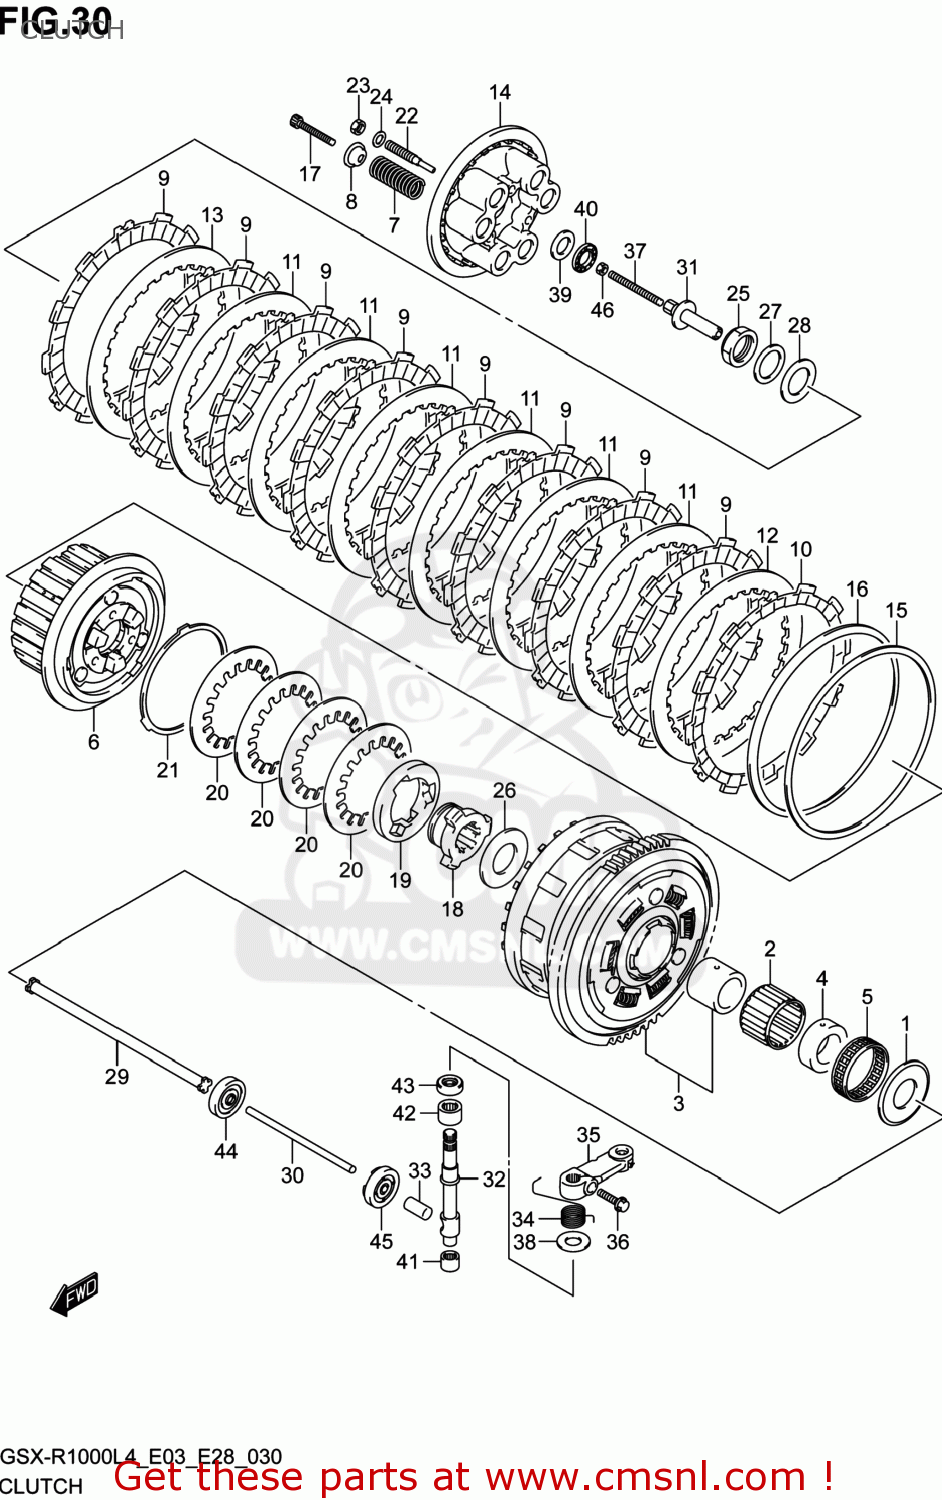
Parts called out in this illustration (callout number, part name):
1	WASHER(25X54X2.4)
2	BEARING(35X40X26.8)
3	GEAR ASSY,PRI DRIVEN
4	SPACER,OIL PUMP DRIVE SPROCKET
5	BEARING(35X40X12)
6	HUB,CLUTCH SLEEVE
7	SPRING,CLUTCH
8	WASHER
9	PLATE,CLUTCH DRIVE NO.1 (NAS)
10	PLATE,CLUTCH DRIVE NO.2 (NAS)
11	PLATE,CLUTCH DRIVEN NO.1 (NAS)
12	PLATE,CLUTCH DRIVEN NO.2 (NAS)
13	PLATE,CLUTCH DRIVEN NO.3 (NAS)
14	DISC,CLUTCH PRESSURE
15	SEAT,WAVE WASHER
16	WASHER,CLUTCH PLATE WAVE
17	BOLT,CLUTCH SPRING
18	CAM,CLUTCH DRIVE
19	CAM,CLUTCH DRIVEN
20	WASHER,CAM REACTION WAVE
21	WASHER,CAM REACTION SEAT
22	LIFTER,CLUTCH PRESSURE DISC
23	NUT,CL PRESS DISC LIFTER LOCK
24	SHIM(8.8X14X1)
25	NUT
26	WASHER(25X50X2.5)
27	WASHER(25X41X2.5)
28	WASHER
29	ROD,CLUTCH
30	ROD,CLUTCH PUSH,L
31	PIECE,CLUTCH PUSH
32	CAMSHAFT,CLUTCH RELEASE
33	CAP,CLUTCH PUSH ROD
34	SPRING,CLUTCH RELEASE RETURN
35	ARM,CLUTCH RELEASE
36	BOLT(6X20)
37	SCREW(6X73)
38	WASHER(10.5X24X1)
39	WASHER(15.5X28X1)
40	BEARING(15X28X2)
41	BEARING(10X14X10)
42	BEARING(12X18X12)
43	SEAL,OIL(10X20X6)
44	SEAL,OIL(6X34X10.5)
45	SEAL,OIL(10X17X5)
46	NUT
